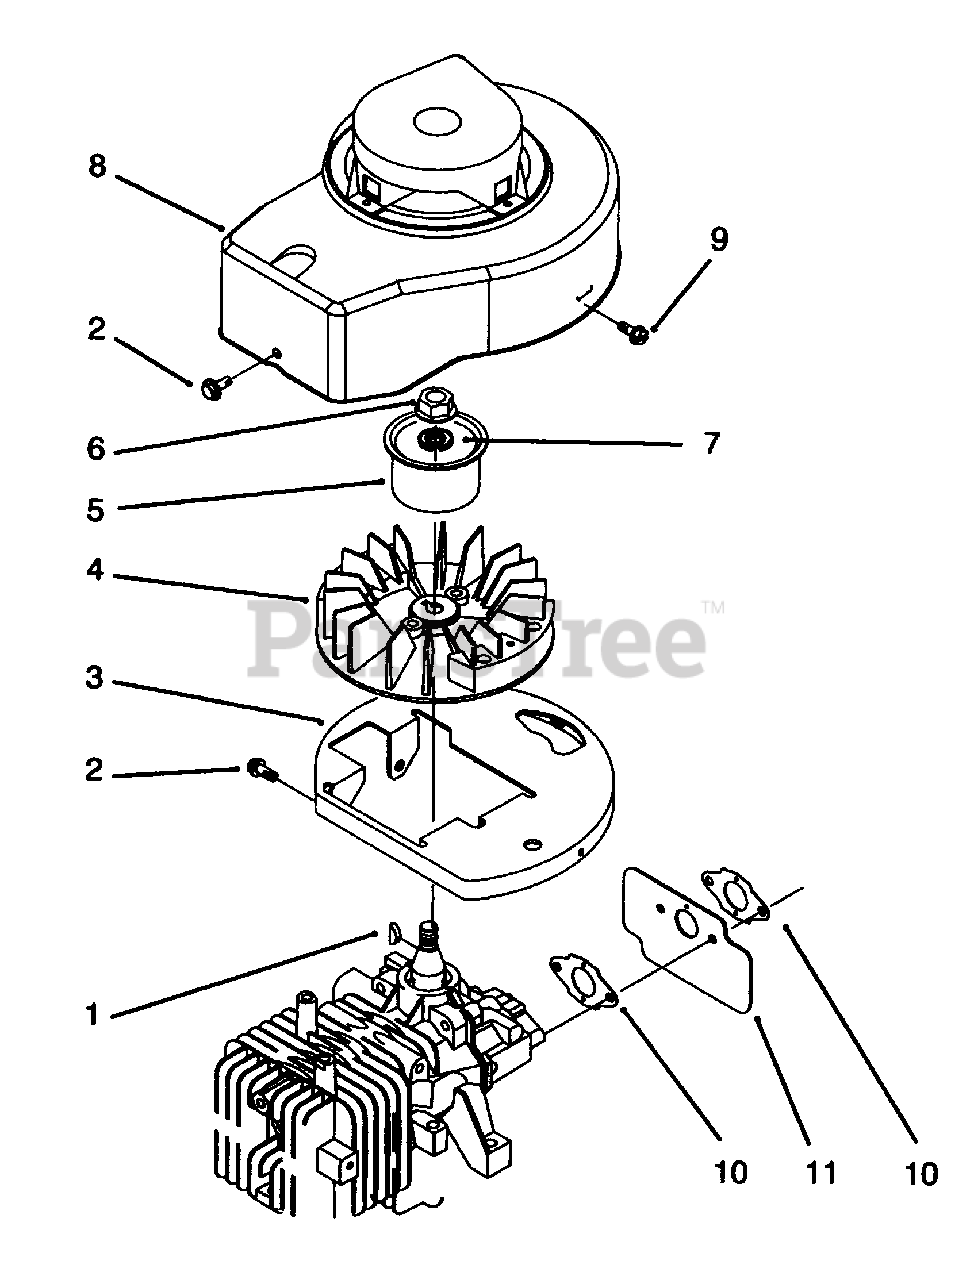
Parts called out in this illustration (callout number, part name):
1	Key-Crankshaft
2	Screw
3	Base-Shroud
4	Flywheel Assembly
5	Hub-Starter
6	Nut-Hex. Flange
7	Washer-Lock
8	Shroud Assembly
10	Gasket-Carburetor
11	Shield-Carburetor
